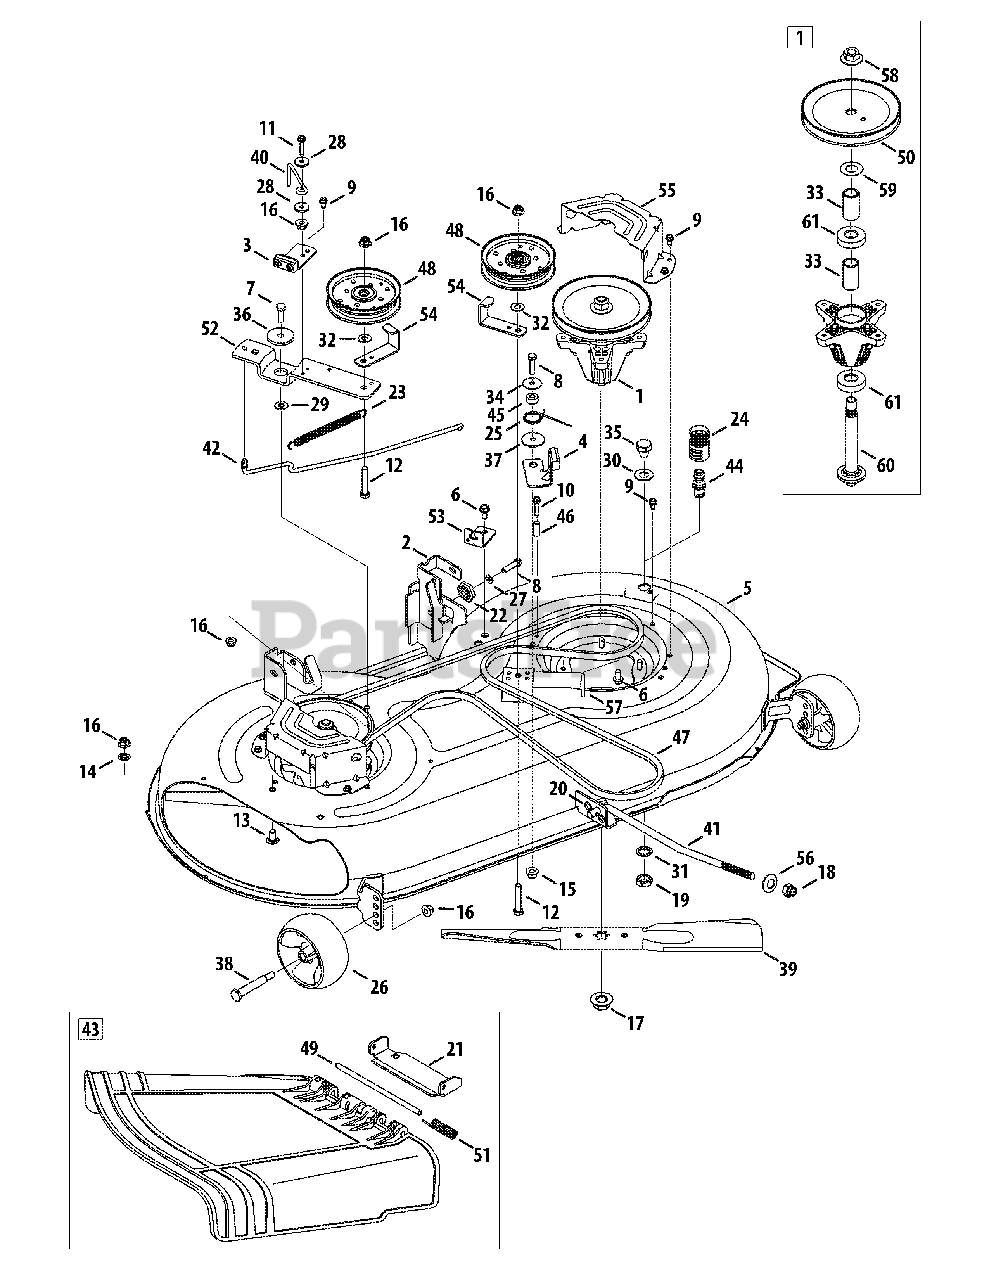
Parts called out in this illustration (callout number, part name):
1	Pulley Spindle Ass’y 6.3 dia.
2	Deck Hanger Bracket Ass'y LH
3	Deck Brake Assembly
4	Deck Brake Assembly
5	Deck Assembly, 42" w/ deck wheels
6	S-Tapp Scr 5/16-18 x .75
7	Hex. Hd. Cap Scr. 3/8-16 x 1.0 Gr. 5
8	Hex Wash Tap Scr 5/16-18 x 1.25
9	Hex Wash S-Tapp Scr 1/4-20 x .50
10	Hex Wash HD Bolt 1/4-20 x 1.50" Lg.
11	Hex Bolt 1/4-20 x 1.25
12	Hex. Hd. Cap Scr. 3/8-16 x 2.0 Gr. 5
13	Carriage Bolt 3/8-16 x .75 Gr. 1
14	Push Nut, 3/8
15	Hex Flange Locknut 5/16-18 Gr. F, Nylon
16	Hex Flange Locknut 3/8-16 Gr. F Nylon
17	Hex Flange Locknut 5/8-18
18	Hex Locknut 1/2-13
19	Hex Nut M16-1.5 DIN 936
20	Bow Tie Cotter Pin
21	Chute Bracket
22	Deck Gear Adjuster
23	Extension Spring .62 dia. x 6.12 Lg.
24	Water Nozzle Adapter
25	Torsion Spring .992 ID x 1.17 OD
26	Deck Wheel 5.0 Dia.
27	L-Wash 5/16 ID
28	Flat Washer .265 ID x .938 OD x .120
29	Flat Washer .385 ID x 1.0 OD x .030
30	Flat Washer .640 ID x 1.24 OD x .06
31	L-Washer Internal
32	Flat Washer .385 ID x .870 OD x .092
33	Spacer .792 x 1.060 x 1.860
34	Flat Washer .330 ID x 1.25 OD x .06
35	Screw Plug M16 x 1.50
36	Shoulder Spacer .8540 x .200
37	Shoulder Spacer .50 Dia x .1475
38	Shoulder Bolt .496 x 2.5, 3/8-16
39	Blade, 21.23", 2-in-1
40	Belt Keeper Rod
41	Front Lift Deck Rod
42	Brake Control Rod
43	Side Discharge Chute Assembly
44	Deck Water Nozzle
45	Spacer .315 x .750 x .375" Lg.
46	Spacer .260 x .375 x 1.030 Lg.
47	V-Belt
48	Idler Pulley w/Flange 4.25 Dia
49	Hinge Pin .3125 diam. x 7.96" Lg.
50	Deck Pulley 6.3 dia.
51	Torsion Spring .44 ID x 2.0
52	Idler Pivot Bracket
53	Deck Cable Engagement Bracket
54	Belt Guard Pulley Bracket
55	Belt Cover
56	Deck Lift Pivot Cup
57	Deck Support Station ary Idler Brkt.
58	Hex Flange Locknut 5/8-18
59	Flat Washer .760 ID x 1.5 OD
60	Spindle Shaft 6.11" Lg.
61	Ball Bearing .787 ID x 1.85 OD x .551
